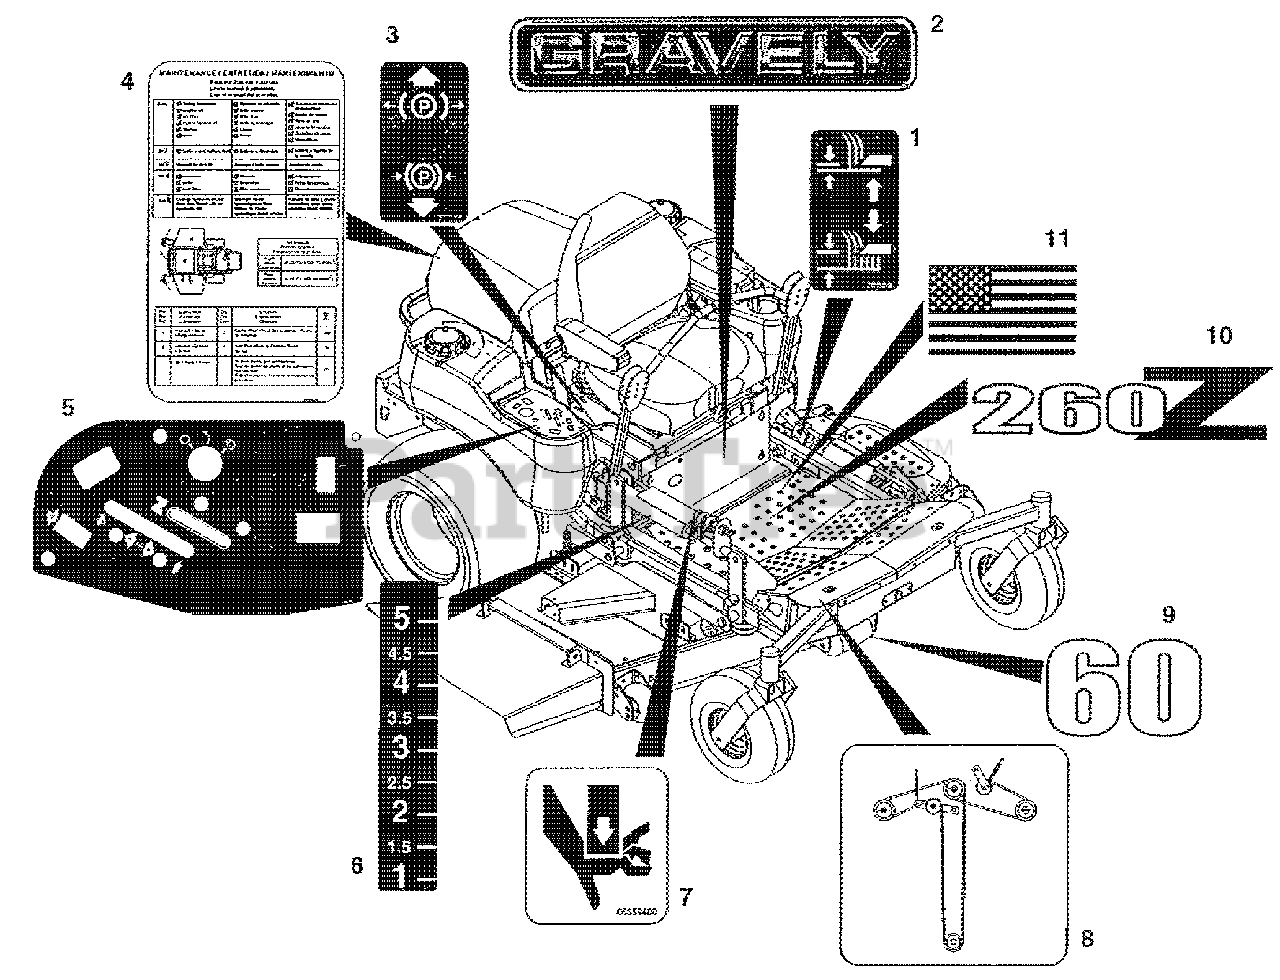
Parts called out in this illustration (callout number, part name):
1	Decal, Lift Lever
2	Decal, 15 in. Gravely Logo
3	Decal, Parking Brake Lever
4	Decal, Service Instructions
5	Decal, Control Panel (066, 067, 068, 070, 071, 072)
6	Decal, Height of Cut
7	Decal, Pinch Point
8	Decal, Belt Diagram (066, 067, 068, 069, 071, 072)
9	Decal, 60 (067, 068, 069, 072)
10	Decal, PM-260Z (067, 068, 069, 072)
11	Decal, American Flag
